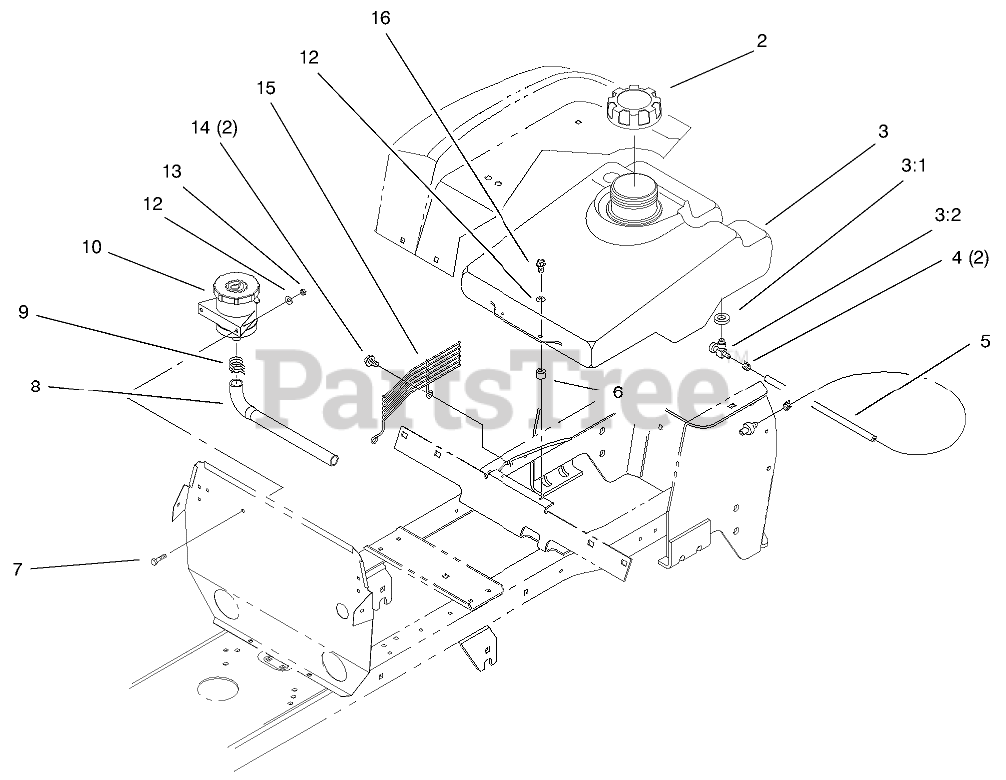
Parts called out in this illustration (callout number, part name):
2	GAS CAP ASM
3	TANK-GAS
3:1	VALVE-FUEL
3:2	BUSHING
4	CLAMP-HOSE
5	HOSE - FUEL LINE TWIN
6	SPACER - FUEL TANK
7	SCREW-HH
8	HOSE - HYDRO
9	CLAMP-HOSE
10	ASS'Y-RESERVOIR
12	WASHER-FLAT
13	NUT-LOCK, NI
14	Screw-HWH (Only On: 72105)
15	Guard-Fan (Only On: 72105)
16	SCREW-HH
